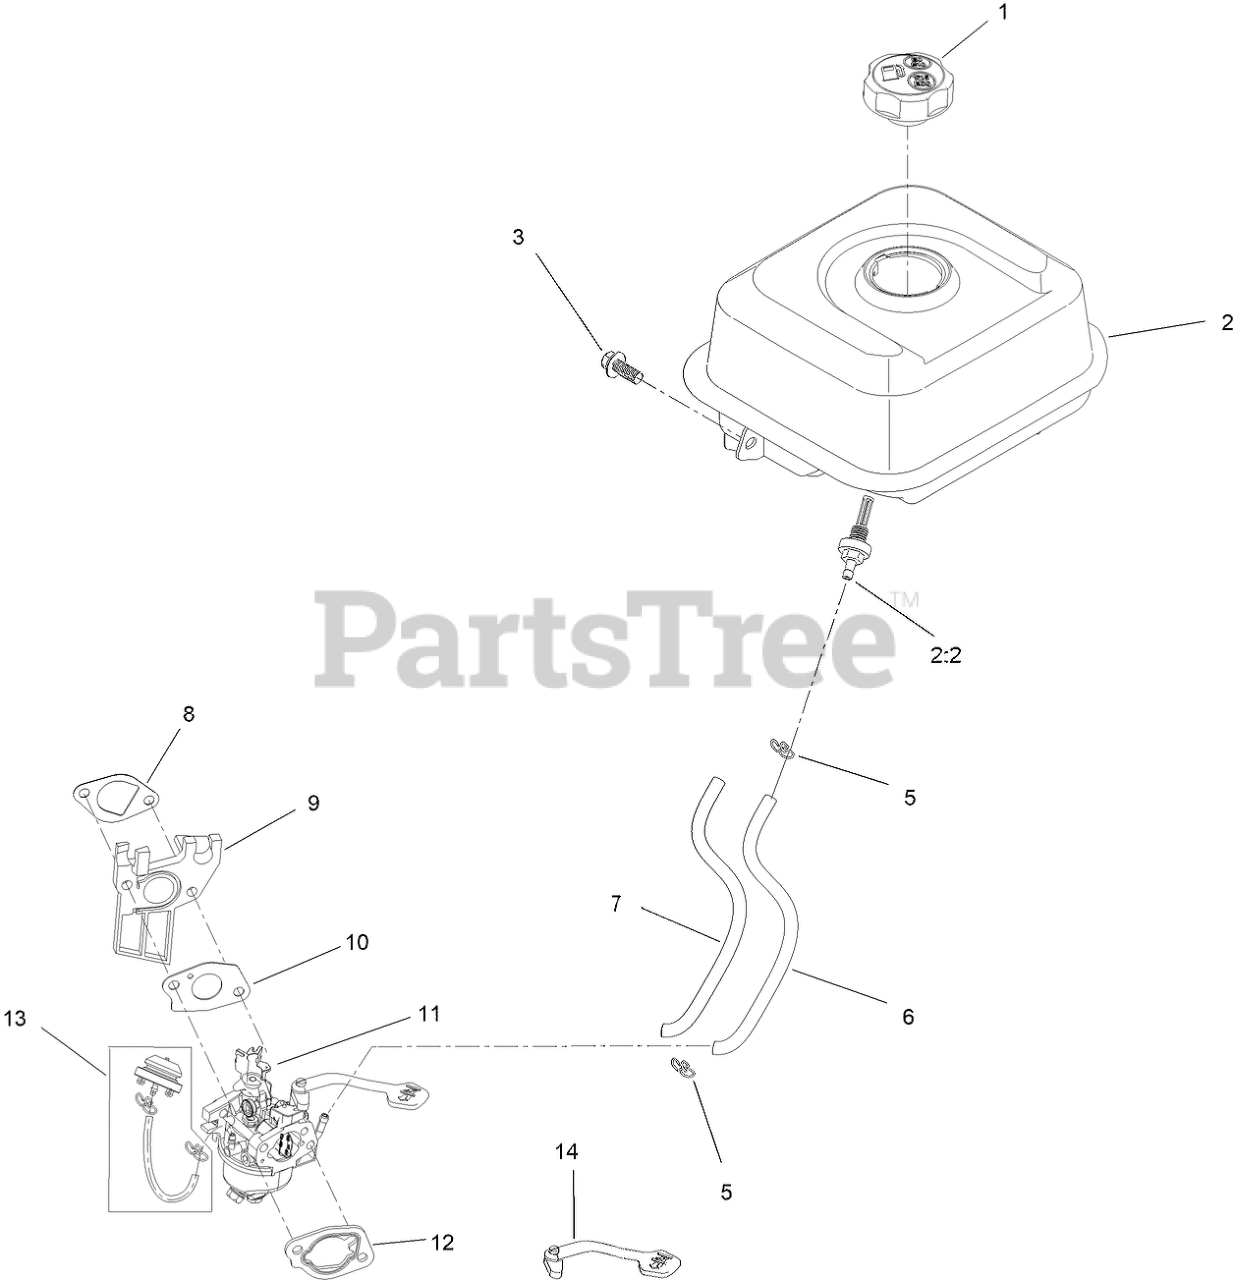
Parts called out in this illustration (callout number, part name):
1	CAP-FUEL
2	FUEL TANK AND FILTER ASM
2:2	FILTER-FUEL
3	SCREW-HHF
5	CLIP-HOSE
6	HOSE-FUEL
7	SLEEVE-ABRASION
8	GASKET-CARBURETOR
9	INSULATOR-CARBURETOR
10	GASKET-CARBURETOR
11	CARBURETOR ASM
12	GASKET-CARBURETOR
13	PRIMER KIT
14	LEVER-CHOKE
